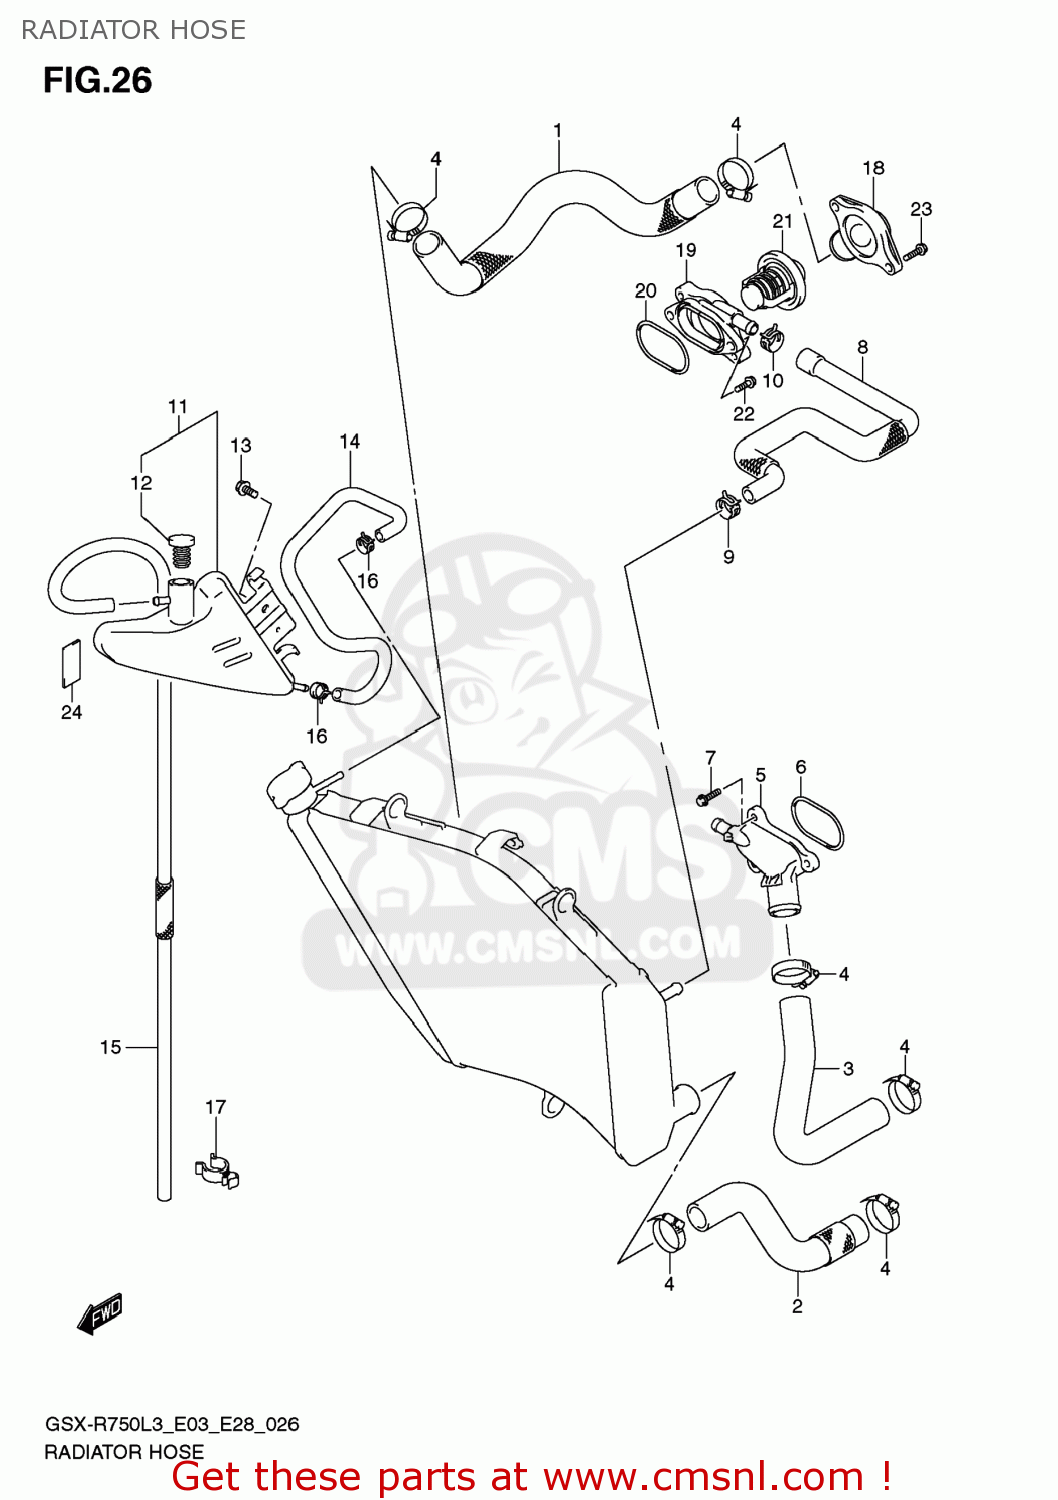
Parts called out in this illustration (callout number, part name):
1	HOSE,RADIATOR INLET
2	HOSE,RADIATOR OUTLET
3	HOSE,CYLINDER INLET
4	CLAMP
5	CONNECTOR,CYLINDER WATER INLET
6	O RING,CYL WATER CONNECTOR
7	BOLT
8	HOSE,WATER BYPASS
9	CLAMP
10	CLIP
11	TANK ASSY,RESERVOIR
12	CAP,RESERVOIR TANK
13	BOLT(6X12)
14	HOSE,RESERVOIR TANK INLET
15	HOSE,RESERVOIR TANK OVFL
16	CLIP
17	CLAMP(L:45)
18	COVER,THERMOSTAT
19	CONNECTOR,THERMOSTAT
20	O RING,THERMOSTAT CONNECTOR
21	THERMOSTAT,WATER 82 DEG
22	BOLT
23	BOLT
24	CUSHION,FR
